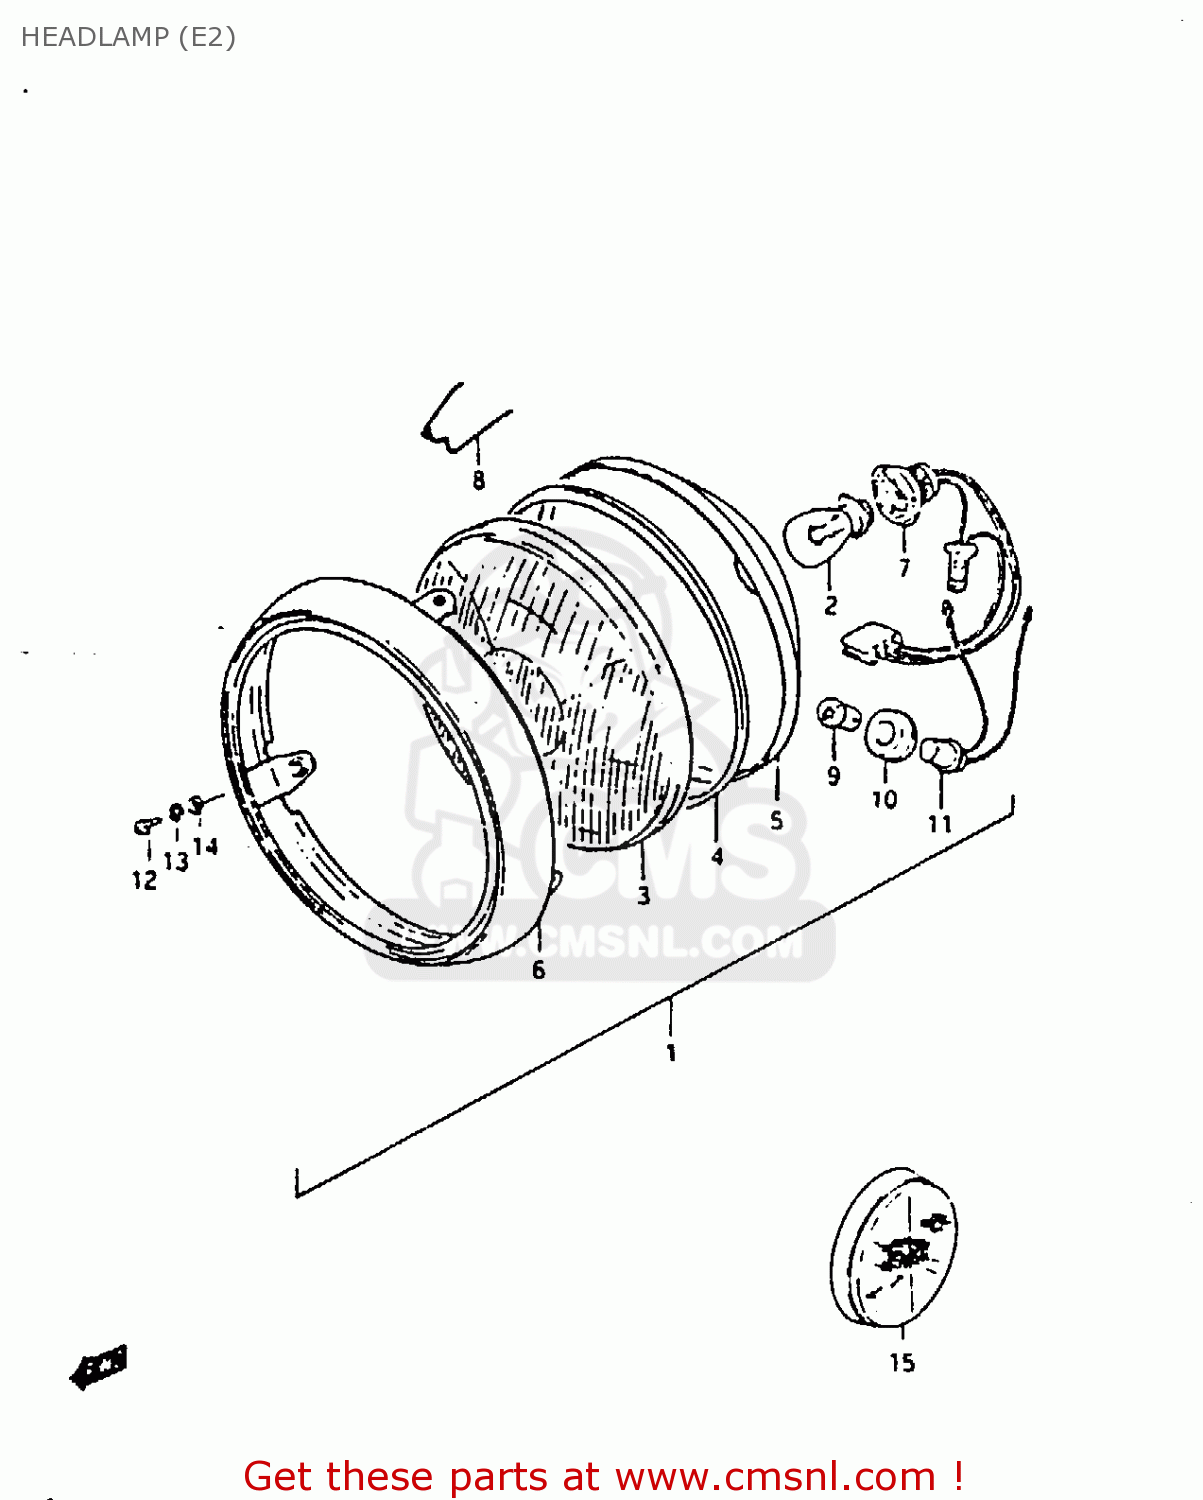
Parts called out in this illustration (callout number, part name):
1	HEADLAMP ASSY
2	BULB(6V25/25W,STANLEY,A7007)
3	LENS
4	GASKET (NAS)
5	REFLECTOR
6	RIM,HEAD LAMP
7	SOCKET
8	SPRING
9	BULB(6V/3W)
10	SEAL,PARKING BULB
11	SOCKET
12	SCREW
13	LOCK WASHER
14	WASHER
15	REFLECTOR,REFLEX
